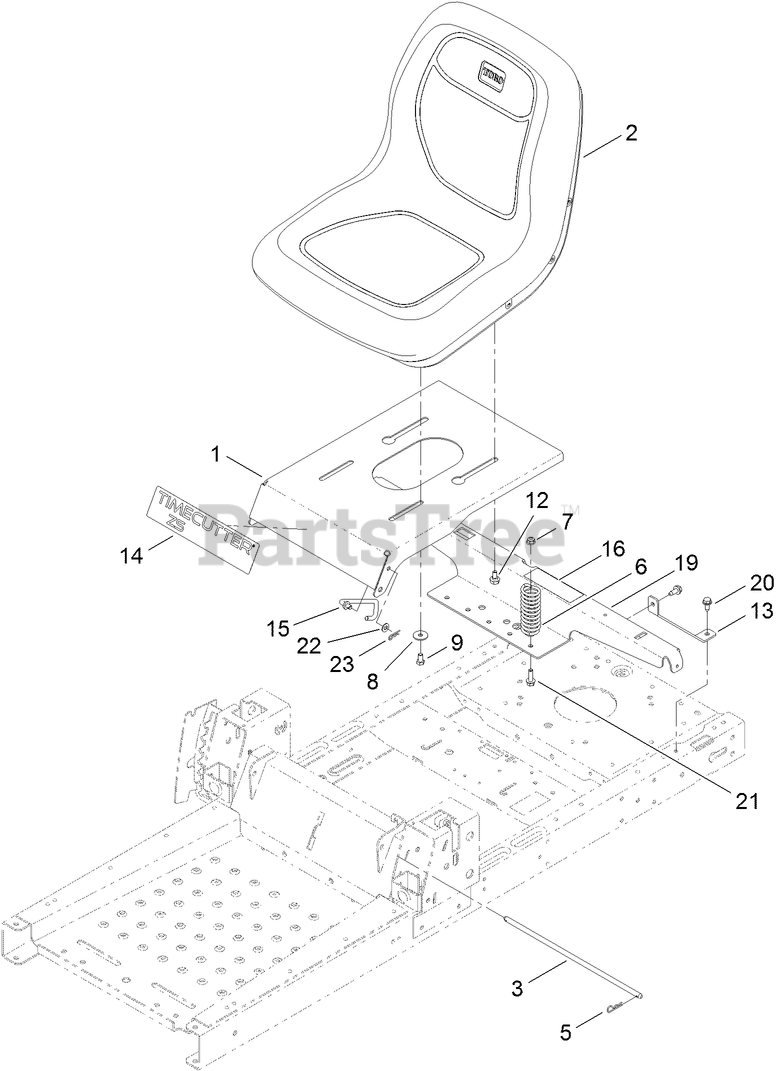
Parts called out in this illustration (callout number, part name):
2	SEAT-18 INCH
3	ROD-PIVOT, NARROW
5	PIN-COTTER
6	SPRING-COMPRESSION
7	NUT-HF, NI
8	WASHER-PIVOT
9	SCREW-HH
12	BOLT-SHOULDER,HFH
13	SUPPORT-TANK, REAR
14	DECAL-TIMECUTTER
15	STOP-SEAT
16	DECAL-SERVICE, CE
19	SUPPORT-POD
20	SCREW-HWHTF
21	SCREW-HHF
22	WASHER-PLAIN
